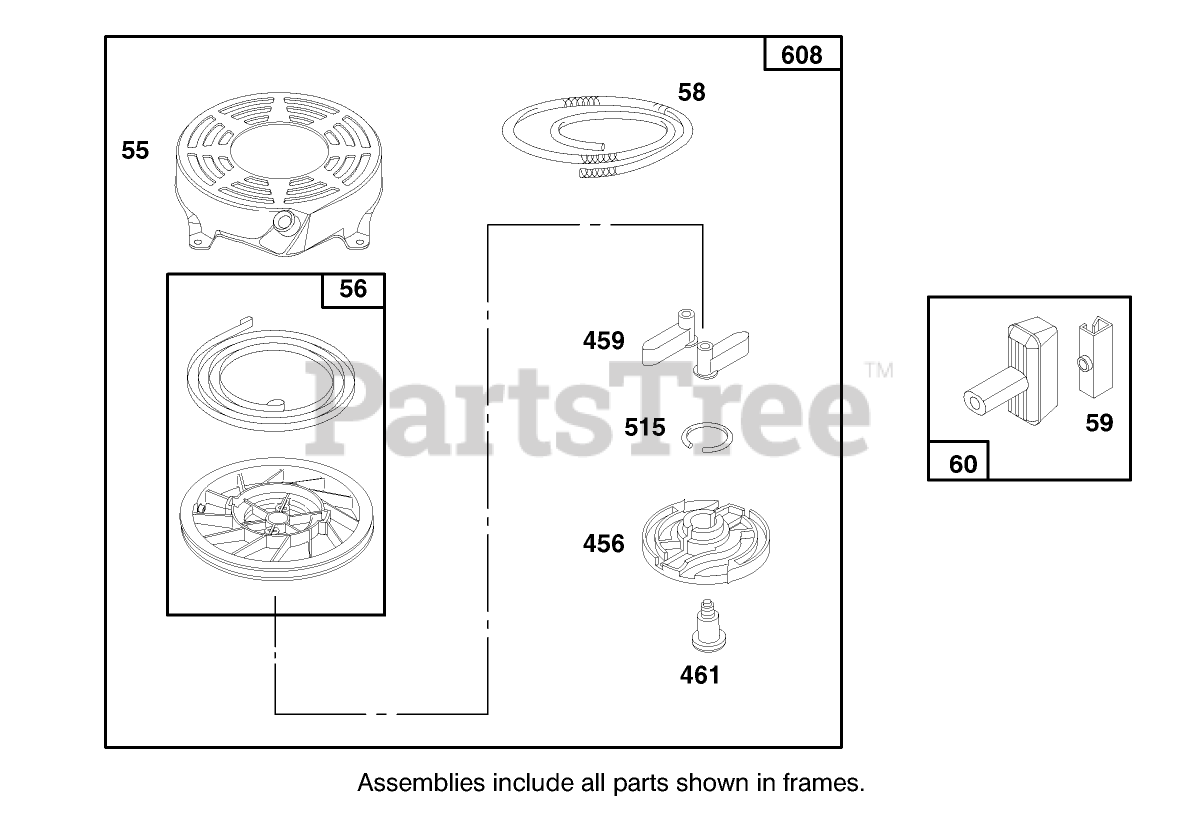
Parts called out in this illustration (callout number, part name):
55	Rewind StarterHousing
56	Pulley and Spring ASM
58	Rope?Starter (Cut to Required Length)
59	Insert-Starter Grip
60	Handle-Rewind Starter
456	Retainer-Spring
459	Ratchet-Pawl
461	Pin-Starter
515	Spring-Torsion
608	Starter-Rewind
